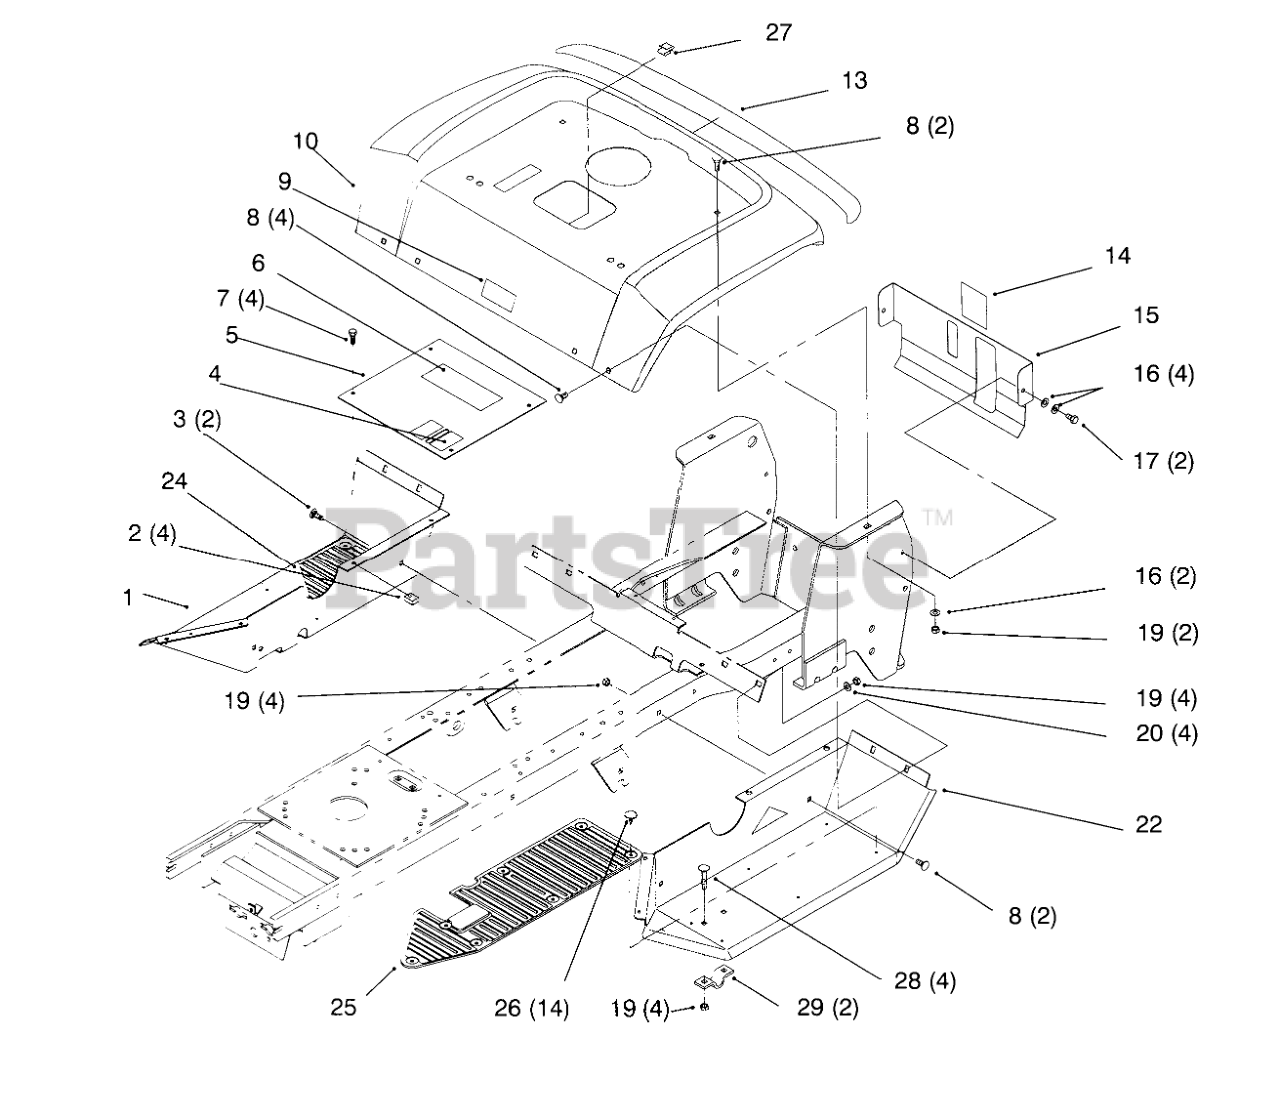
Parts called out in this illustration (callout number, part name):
1	FOOTREST-RH
2	Nut-Retainer
3	SCREW-CARR
4	DECAL - HOC
5	PLT - FTREST W/DECAL
6	DECAL-DANGER
7	SCREW-HH
8	BOLT-CARR
9	DECAL - USA
10	Fender
13	DECAL - REAR FENDER
14	DECAL-LEVEL, FUEL
15	COVER-REAR
16	WASHER-PLAIN
17	SCREW
19	NUT-LOCK, NI
20	WASHER-FLAT
22	FOOTREST-LH
24	FOOTPAD-RH
25	FOOTPAD-LH
26	FASTENER-PANEL
27	CLIP-RETAINER, WIRE
28	SCREW-CARR
29	CLAMP
